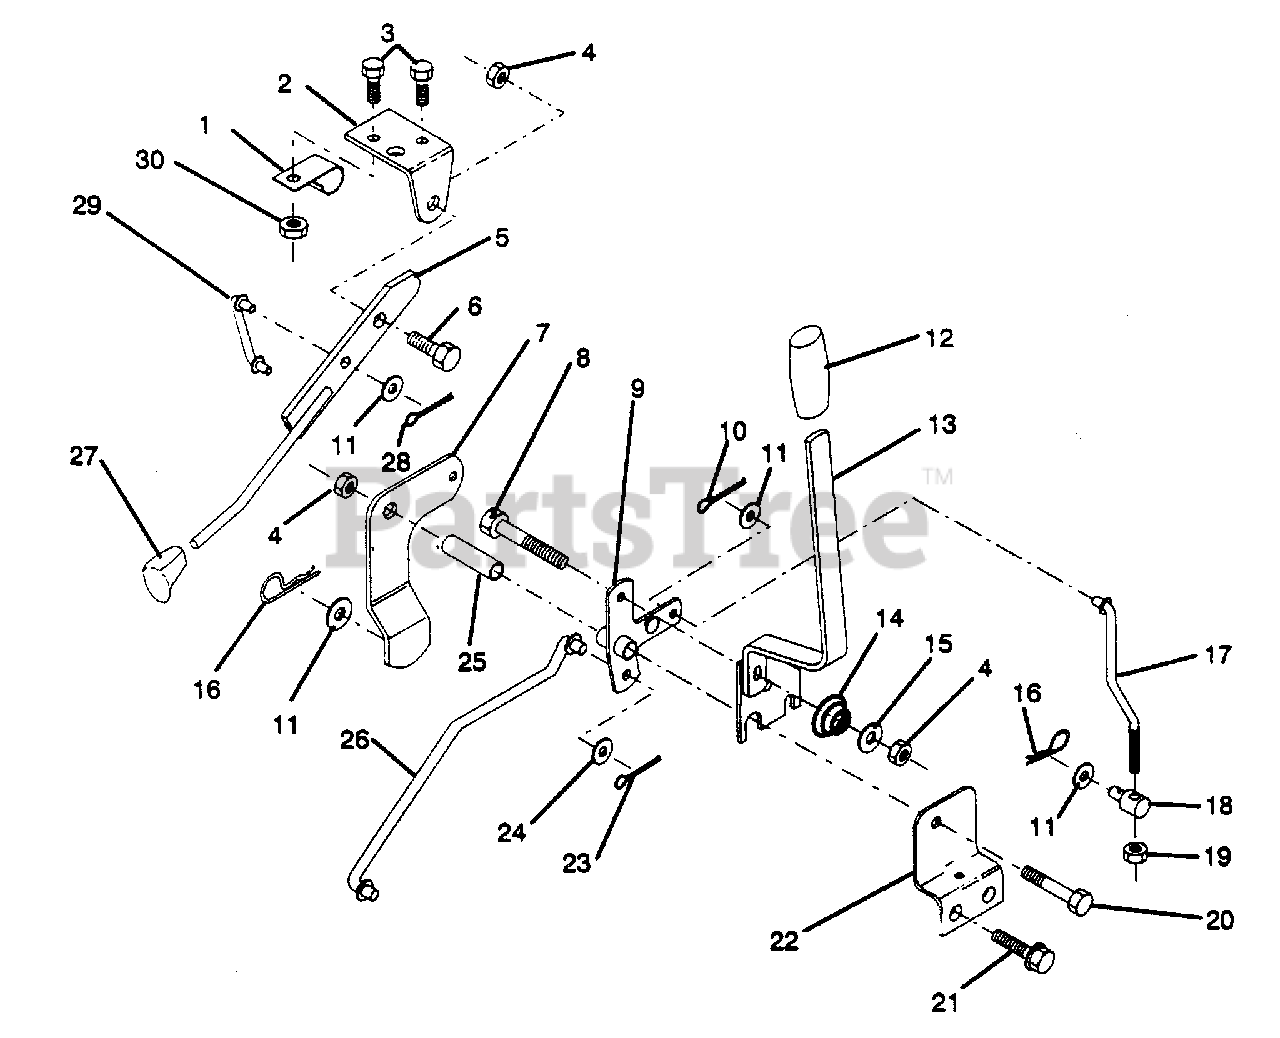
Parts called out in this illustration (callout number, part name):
1	Clip, Insulated (AYP part number)
2	Bracket, Mower Clutch (AYP part number)
3	Bolt, Fin. Hex 1/4-20 UNC x 1/2 Gr. 5 (AYP part number)
4	Nut, Crownlock 3/8-16 UNC
5	Assembly, Clutch Lever (AYP part number)
6	Bolt, Shoulder (AYP part number)
7	Assembly, Mower Clutch Arm (AYP part number)
8	Bolt, Hex 3/8-16 UNC x 2-1/4 (AYP part number)
9	Assembly, Bellcrank Lift (AYP part number)
10	Pin, Cotter 1/8 x 3/4 (AYP part number)
11	Washer, 13/32 x 13/16 x 16 Ga. (AYP part number)
12	Grip, Handle (AYP part number)
13	Assembly, Lift Handle (AYP part number)
14	Spring, Compression (AYP part number)
15	Washer 13/32 x 3/4 x 12 Ga. (AYP part number)
16	Retainer, Spring (AYP part number)
17	Link, Front Lift (AYP part number)
18	Trunnion, Threaded 3/8-16 (AYP part number)
19	Nut, Hex Jam 3/8 x 16 UNC (AYP part number)
20	Bolt, Fin. Hex 3/8-16 UNC x 2-3/4 (AYP part number)
21	Screw, Hex Thdrol. 5/16-18 x 1/2 (AYP part number)
22	Bracket, Mower Height (AYP part number)
23	Pin, Cotter 1/8 x 1 (AYP part number)
24	Washer 17/32 x 1 x 16 Ga. (AYP part number)
25	Tube, Spacer (AYP part number)
26	Rod, Mower Lift (AYP part number)
27	Knob (AYP part number)
28	Pin, Cotter 3/32 x 3/4 (AYP part number)
29	Link, Mower Clutch (AYP part number)
30	Nut, Crownlock 1/4-20 (AYP part number)
